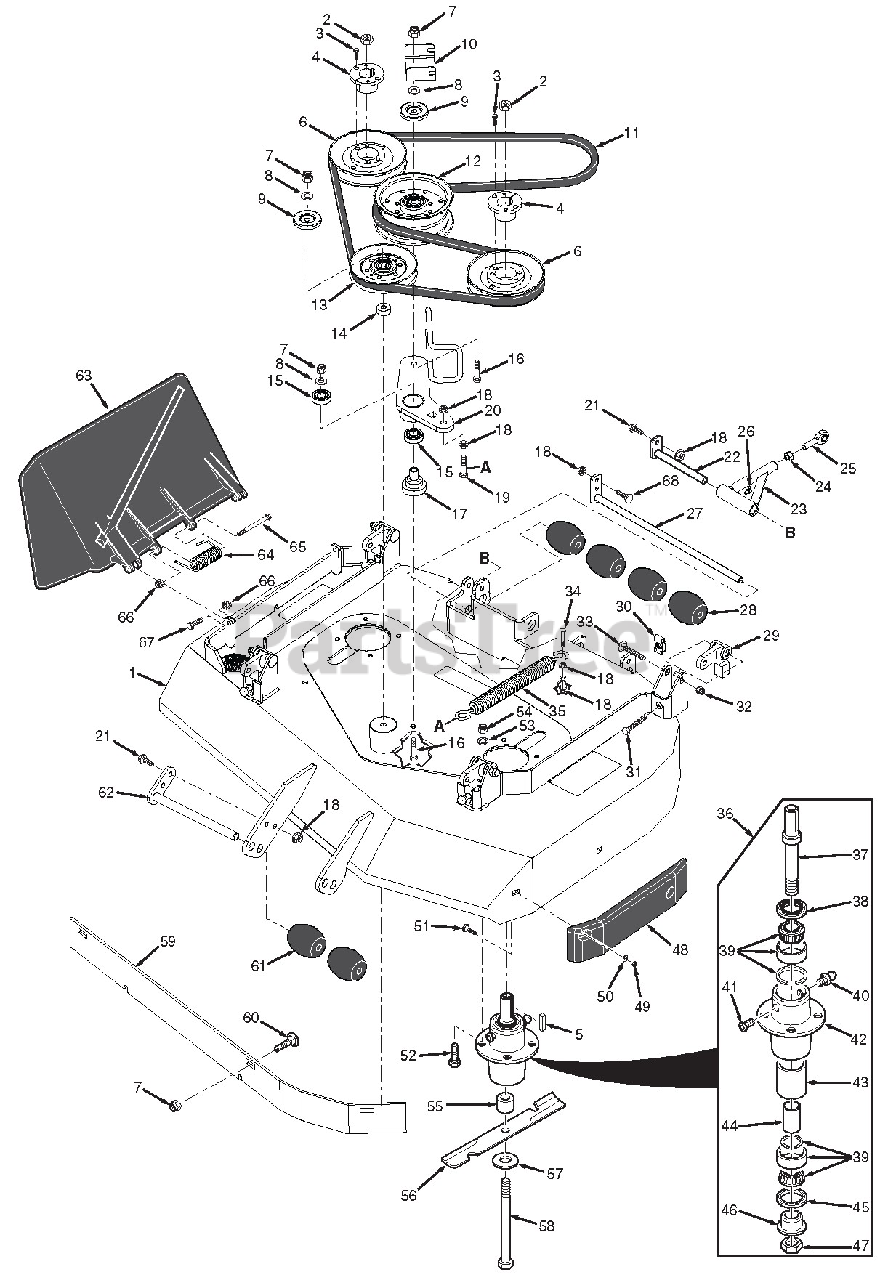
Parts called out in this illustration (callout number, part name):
1	Cutter Deck w/Decals - 36A
2	Nut, 5/8-11 UNC
3	Bolt, Hex Head 1/4-20 x 1"
4	Tapered Hub, 1.125" Bore
5	Key, 1/4 x 1/4 x 2"
6	Pulley, 5.73 OD Tapered Bore
7	Nut, Elastic Stop 3/8-16
8	Flatwasher, 3/8-.391 x .938 x .105
9	Dust Shield
10	Bracket, Belt Guide
11	Belt, Cutter Deck
12	Pulley, 5" Idler
13	Pulley, Idler
14	Spacer
15	Bearing
16	Bolt, Hex Head 3/8-16 x 3-1/4"
17	Pivot, Idler
18	Nut, Serrated Flange 3/8-16
19	Bolt, Hex Head 5/16-18 x 1-1/2" Gr.8
20	Idler Arm Assy.
21	Bolt, Hex Head 5/16-18 x 1"
22	Shaft Weldment, Pusharm Mount
23	Pusharm Assy., LH
23	Pusharm Assy., RH
24	Nut, 1/2-20 UNF
25	Rod End, 1/2-20 RH
26	Grease Fitting
27	Shaft Weldment
28	Wheel, Anti-Scalp
29	Lever, Deck Level
30	U-Nut, 3/8-16
31	Bolt, Hex Head 3/8-16 x 2" Special
32	Nut, Elastic Stop 7/16-14
33	Bolt, Carriage 7/16-14 x 2-1/4"
34	Bolt, Hex Head 3/8-16 x 1-1/2" Gr.8
35	Spring
36	Spindle Assembly
37	Shaft, Spindle
38	Seal, Upper
39	Bearing Assembly
40	Grease Fitting
41	Valve, Grease Relief
42	Housing, Spindle
43	Spacer, Outside
44	Spacer, Inside
45	Seal, Lower
46	Bushing, Lower
47	Nut, Special 1-1/16" - 18
48	Pad, Deck Wear
49	Nut, Center Lock 5/16-18
50	Flatwasher, 5/16-.344 x .688 x .065
51	Bolt, Carriage 5/16-18 x 1-3/4"
52	Bolt, Hex Head 5/16-18 x 1-3/4"
53	Lockwasher, 5/16" Spring
54	Nut, Elastic Stop 5/16-18
55	Spacer, Spindle Bottom
56	Cutter Blade, 18"
57	Flatwasher, 5/8-.688 x 1.75 x .134 HD
58	Bolt, Hex Head 5/8-11 x 9-1/2"
59	Baffle, Flange 36A
60	Bolt, Carriage 3/8-16 x 1"
61	Wheel, Anti-Scalp
62	Shaft Weldment
63	Discharge Chute Assembly
64	Spring, Discharge Chute
65	Bolt, Hex Head 5/16-18 x 4-3/4"
66	Nut, Elastic Stop 5/16-18
67	Bolt, Hex Head 5/16-18 x 1-3/4"
68	Bolt, Carriage 5/16-18 x 1"
